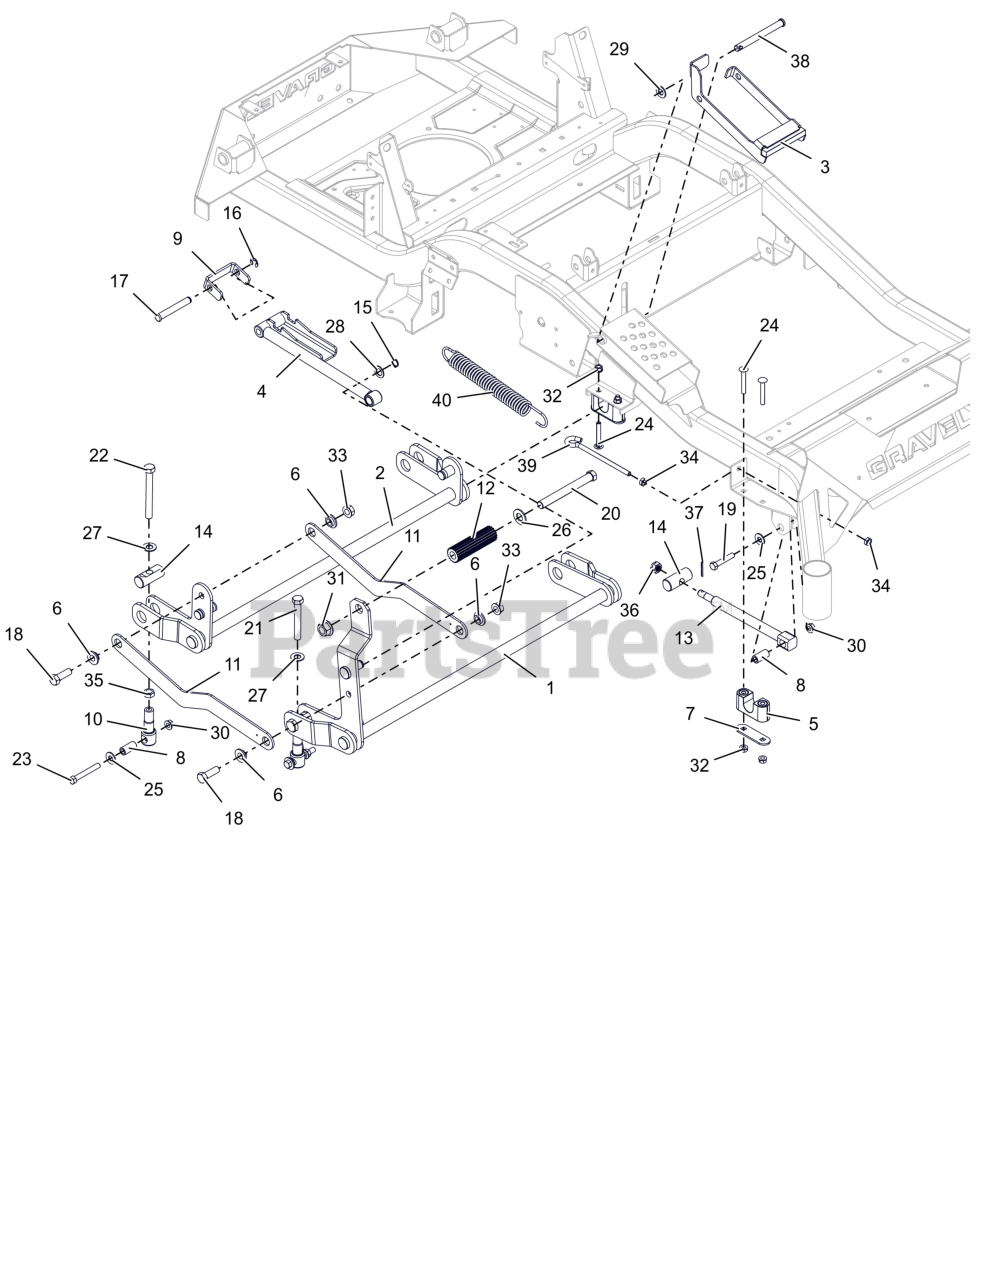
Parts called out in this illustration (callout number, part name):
1	WLDMT, FRONT DECK LIFT PIVOT
2	WLDMT, REAR DECK LIFT PIVOT
3	WLDMT, HOC TRANSFER LOCK (BLACK)
4	WLDMT, HOC LIFT ARM (BLACK)
5	ASM-BUSHING, DECK LIFT
6	BSHG-FLG .515X.750X.310X1.120
7	PLATE, BEARING SUPPORT
8	SPACER, DECK LEVELING
9	BRKT, HOC LINE
10	LINK, DECK LIFT FORMED
11	LINK, DECK
12	ROD, FOOT PEDAL (BLACK)
13	DRAG,LINK-HD
14	PIN, DECK LIFT
15	RG-RTNG-EXT .625X.050
16	RG-RTNG-EXT .500X.042 (E)
17	PIN, .499/.494 x 3.385 CLEVIS
18	BLT,HEX .50-13X1.50 G5 ZCC
19	BLT,HEX .38-16X2.00 G5 ZCC
20	BLT, HEX .62-11X5.50 G5 FBP
21	BLT, HEX 0.5-13X3.5F GR5 ZCC
22	BLT, HEX .50-13X4.50F G8 ZCC
23	BLT, HEX .38-16X2.75 G8 ZCC
24	BLT, RHSSN.31-18X2.25 G5 ZCC
25	WSHR,FLT .438X1.00X.083 ZCC
26	WSHRFLT 5/8SAE CARBHARD FBP
27	WSHR, FLT .557X1.040X.102 ZCC
28	WSHR, FLT .630X1.005X.062 ZCC
29	WSHR-FL-NYL .518X1.000X.080
30	NUT-LK-TOP-FLG .38-16 ZC120
31	NUT,FLG-TOP LK .625-11 FBP
32	NUT,LK-CTR-FLG .31-18 GF ZCC
33	NUT-LK-TOP-FLG .500-13 GF ZCC
34	NUT-JAM .375-16 G2 ZCC
35	NUT-JAM .500-13 G2 ZCC
36	NUT-SL .50-13
37	PIN,CTR.12X1.25EXTPRSQCT ZC120
38	PIN, SLIC-.500X4.97X4.55 -ZC
39	BOLT,.38-16 X 5.25-.62 DIA EYE
40	SG-TENS .162X1.25X8.25 WLD 25
